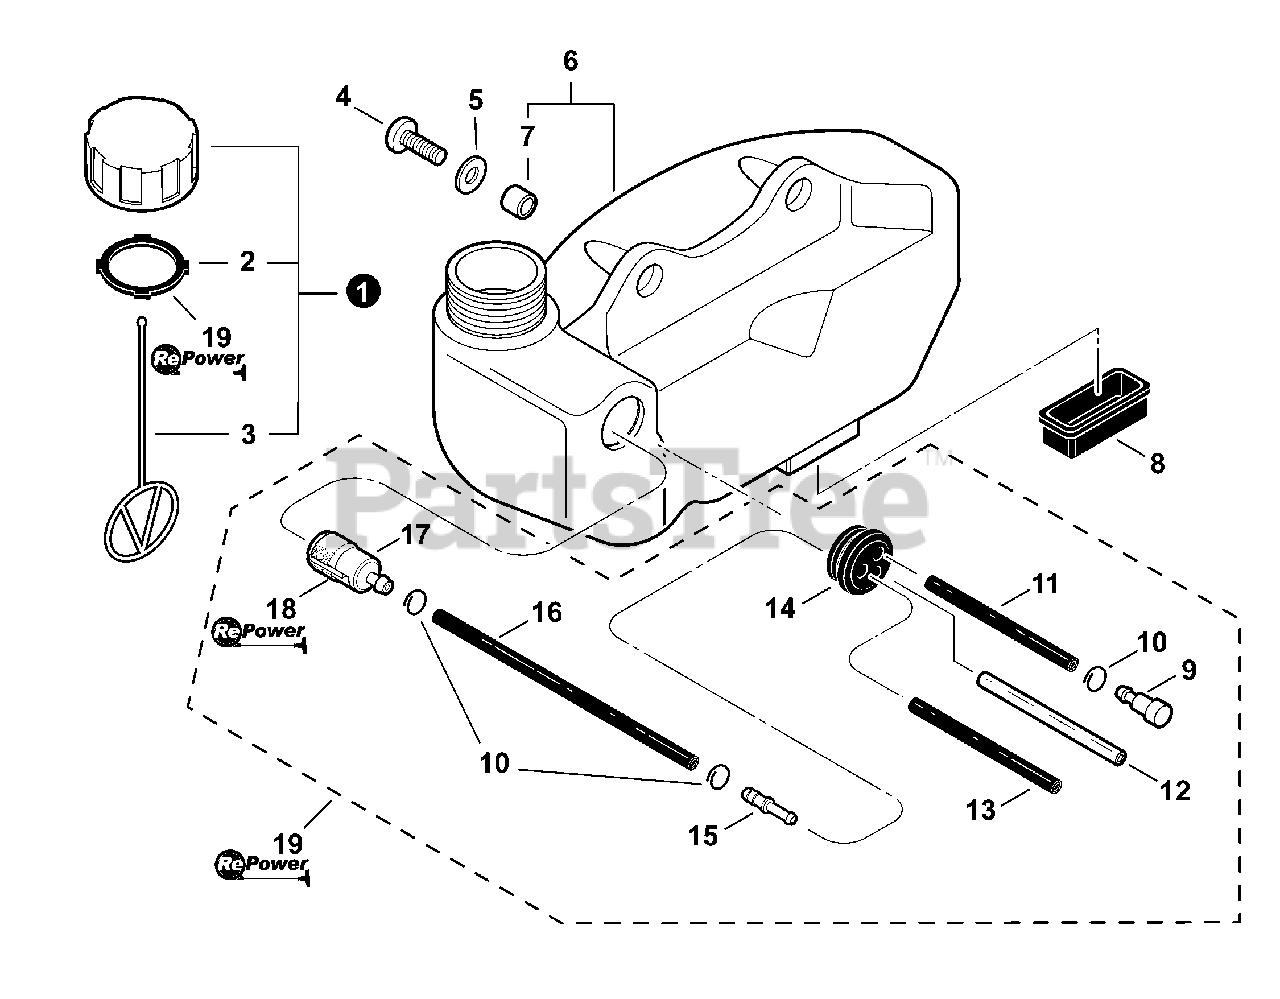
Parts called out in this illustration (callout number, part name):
1	CAP ASSY, FUEL
2	GASKET, FUEL CAP
3	CONNECTOR, CAP L= 123
4	BOLT, TORX 5×16
5	WASHER 5.5×12×0.8
6	TANK, FUEL
7	SPACER 6.2×7.8×6
8	CUSHION, FUEL TANK
9	VENT ASSY
11	PIPE, FUEL 3×5×70 BLACK
12	PIPE, FUEL 3×6×75 CLEAR
13	PIPE, FUEL 3×5×74 BLACK
14	GROMMET, FUEL 5
15	CONNECTOR, PIPE 5×3.5
16	PIPE, FUEL 3×5×115
17	FILTER, FUEL
18	TUNE-UP KIT - REPOWER
19	FUEL SYSTEM KIT - REPOWER
